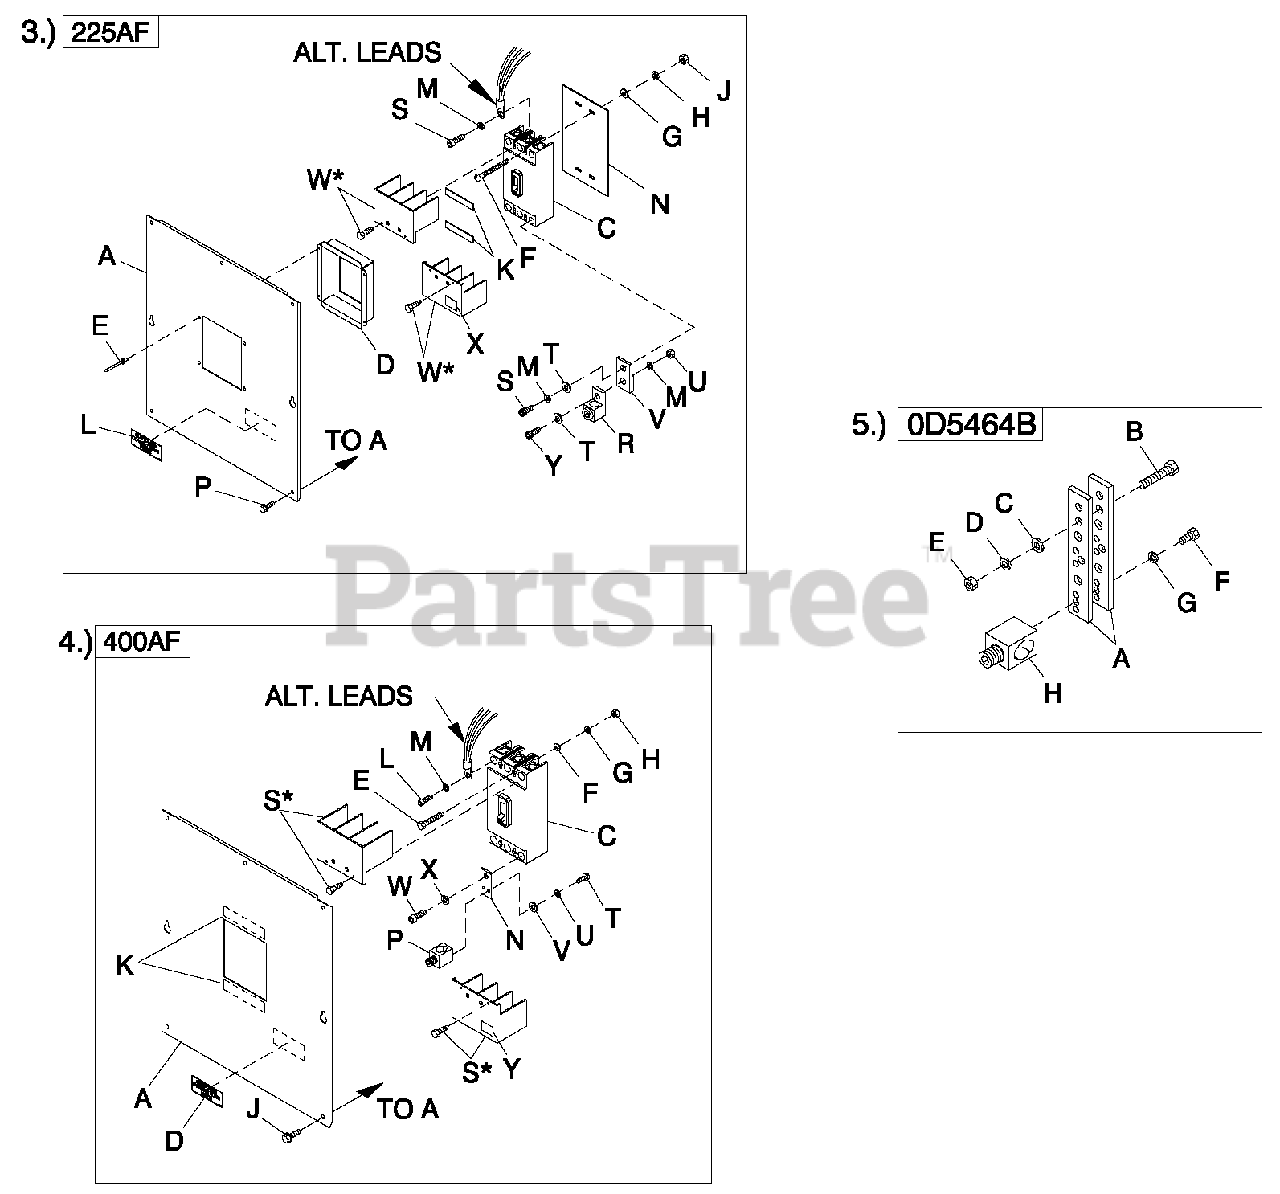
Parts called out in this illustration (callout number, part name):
A	COVER CBC5 225AF
C	CIRCUIT BREAKERS 200A FRAME
D	COVER CB DISH 225AF
E	RIVET POP .125 X .275 SS
F	SCREW RHM #8-32X3-1/4
G	WASHER FLAT #8 ZINC
H	WASHER LOCK #8-M4
J	NUT HEX #8-32 STEEL
K	TAPE ELEC 1/2 FOAM
L	DECAL CUSTOMER CONNECT INSIDE
M	WASHER LOCK M8-5/16
N	INSULATOR CB225AF
P	SCREW THF M6-1 X 16 N WA Z/JS
R	LUG SLDLSS 300 MCM-6 AL/CU
S	SCREW SHC M8-1.25X20G8
T	WASHER FLAT 5/16-M8 ZINC
U	NUT HEX M8-1.25G8 CLEAR ZINC
V	BUS BAR 200A LUG ADAPTOR
W	TERMINAL COVER CB
X	DECAL TERMINAL SHOCK HZD BI
Y	SCREW SHC M8-1.25 X 25 G12.9
A	COVER CBC5 400AF
C	CIRCUIT BREAKERS 400A FRAME
D	DECAL CUSTOMER CONNECT INSIDE
E	SCREW RHM 10-32X4
F	WASHER FLAT #10 ZINC
G	WASHER LOCK #10
H	NUT HEX #10-32 STEEL
J	SC RE W THF M6-1 X 16 N WA Z/JS
L	SCREW SHC M10-1.5X 25 G12.9
M	WASHER LOCK M10
N	BUS BAR CB ADAPTER 225-400 A
P	LUG SLDLSS 600/250-1/0 X 1/4-28
R	WASHER FLAT 3/8-M10 ZINC
S	TERM COVER CB
T	SCREW HHC 1/4-28 X 1/2 G5
U	WASHER LOCK M6-1/4
V	WASHER FLAT 1/4-M6 ZINC
W	SCREW SHC M10-1.5X 25 G12.9
X	WASHER LOCK M10
Y	DECAL TERMINAL SHOCK HZD BI
A	COVER CBC5 800AF
C	CIRCUIT BREAKERS 800A FRAME
D	INSULATOR CB800AF
E	SCREW RHM 1/4-20X3-1/2
F	WASHER FLAT 1/4-M6 ZINC
G	WASHER LOCK M6-1/4
H	NUT HEX 1/4-20 STEEL
J	SCREW THF M6-1X16 N WAZ/JS
L	SCREW SHC M10-1.50 X 40 G12.9
M	WASHER FLAT 3/8-M10 ZINC
N	WASHER LOCK 3/8
P	NUT HEX M10-1.5 G8YEL CHR
R	LUG SLDLSS 3/0-400X3 MCM AL/CU
S	SCREW SHC M6-1.0X 50 G8.8
T	DECAL CUSTOMER CONNECT INSIDE
U	TERM COVER VITZROTECH 400AF CB
V	DECAL TERMINAL SHOCK HZD BI
W	WASHER LOCK M6-1/4
A	BUS BAR NEUTRAL BLOCK 390
B	SCREW HHC M8-1.25 X 45 G8.8 FT
C	WASHER FLAT 5/16-M8 ZINC
D	WASHER LOCK M8-5/16
E	NUT HEX M8-1.25 G8 YEL CHR
F	SCREW HHC 1/4-28 X 3/4 G5
H	LUG SLDLSS 600/250-1/0X1/4-28
